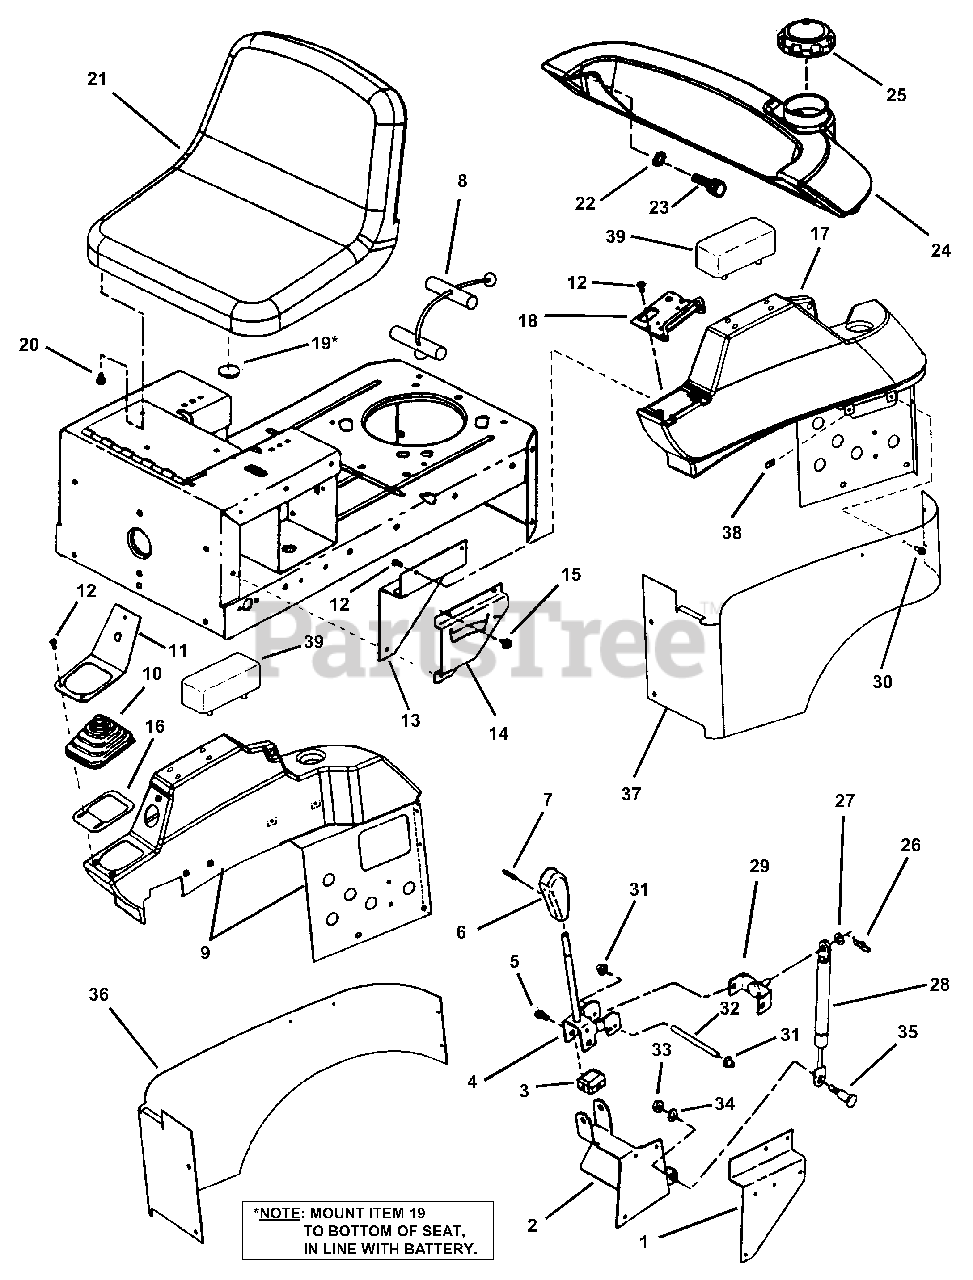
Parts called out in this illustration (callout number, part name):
1	BRACKET, Right Hand Tank Support
2	BRACKET, Joystick
3	PIVOT, Joystick Control
4	HANDLE, Joystick Control
5	BOLT, 5/16-18 x 3/4" Shoulder
6	LEVER, Shift Handle
7	PIN, 3/16 x 3/4" Roll
8	TETHER, Seat
9	ASSEMBLY, R.H. Fender
10	BOOT, Joystick, Rubber
11	BRACKET, Joystick/Key
12	SCREW, 1/4 x 5/8" Pan Head Self-Tapping
13	BRACKET, Left Hand Tank Support
14	BRACKET, Brake/Clutch Detent
15	SCREW, 1/4-20 x 5/8" Self-Tapping
16	SPEED PLATE
17	ASSEMBLY, L.H. Fender
18	GUARD, Throttle Control
19	BUMPER, Battery
20	BOLT, 5/16-18 x 1" Hex Flange Lock
21	SEAT
22	WASHER, 1/4" Internal/External Tooth
23	SCREW, 1/4-20 x 1-1/2" Thumb
24	ASSEMBLY, Fuel Tank
25	CAP, Fuel Tank (w/Gage & Screw Vent)
26	COTTER-PIN, 3/8 Self Locking
27	WASHER, 11/32 x 11/16" Flat
28	CYLINDER, Joystick Control
29	BRACKET, Joystick Control
30	SCREW, #10-24 x 1/2" Machine
31	PUSH-NUT, 1/4"
32	PIN, Joystick
33	NUT, 5/16-18 Hex, Grade 5
34	WASHER, 21/64 Split Lock
35	BOLT, 5/16-18 Shoulder
36	FENDER, R.H. Steel (Radius)
37	FENDER, L.H. Steel (Radius)
38	U-CLIP, #10-24
39	ARM REST,
